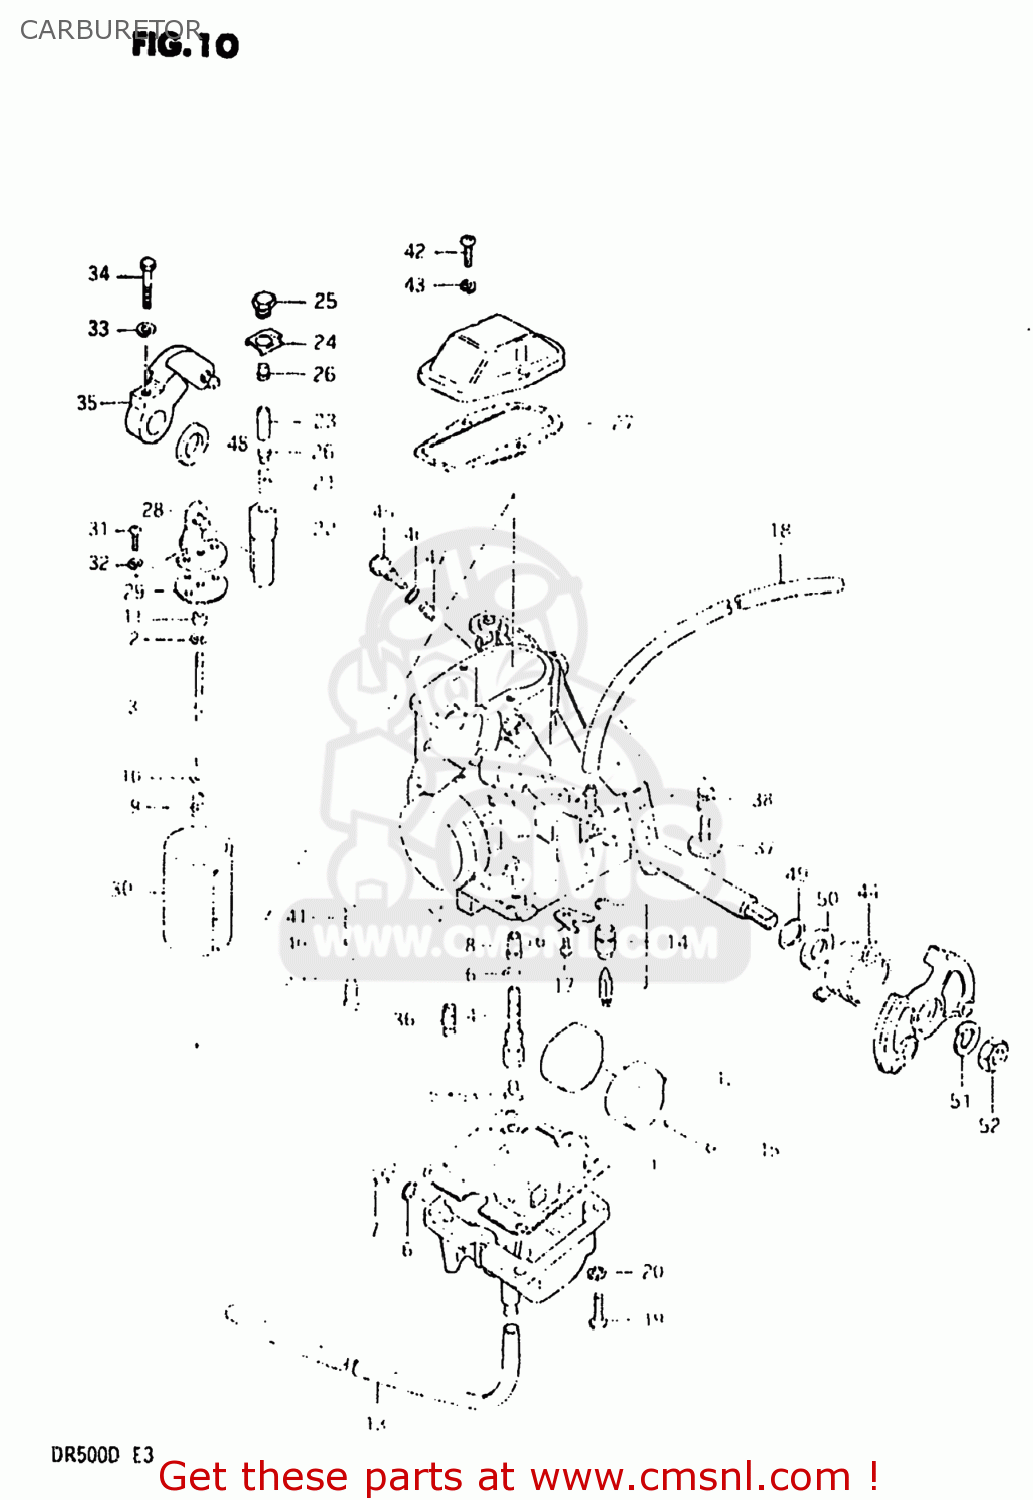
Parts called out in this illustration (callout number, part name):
1	GASKET,FLOAT CAHMBER (NAS)
2	CLIP
3	NEEDLE JET
4	PIPE,BLEEDER
5	JET,MAIN(132.5)
6	O RING
7	SCREW
8	JET,NEEDLE
9	SPRING
10	WASHER,JET NEEDLE
11	RING
12	FLOAT
13	HOSE
14	VALVE ASSY,NEEDLE
15	PIN,FLOAT
16	PLATE
17	SCREW 4X6
18	HOSE
19	SCREW
20	LOCK WASHER
21	SPRING,CARBURETOR
22	LEVER ASSEMBLY
23	SPRING
24	PLATE,CARBURETOR
25	SCREW
26	PIN,CARBURETOR
27	GASKET,MIXING CHAMBER (MCA)
28	CONNECTOR
29	PLATE,THROTTLE VALVE
30	VALVE,THROTTLE
31	SCREW
32	LOCK WASHER
33	WASHER
34	BOLT
35	ARM,THROTTLE
36	JET
37	SCREW
38	SPRING,THROTTLE SCREW
39	ADJUSTER,PILOT
40	O RING
41	SPRING,PILOT AIR SCREW
42	SCREW
43	LOCK WASHER
44	SPRING,THROTTLE VALVE
45	SCREW,PILOT AIR ADJUSTING
46	O RING
47	SPRING
48	RING
49	SEAL
50	RING
51	LOCK WASHER
52	NUT
53	JET
